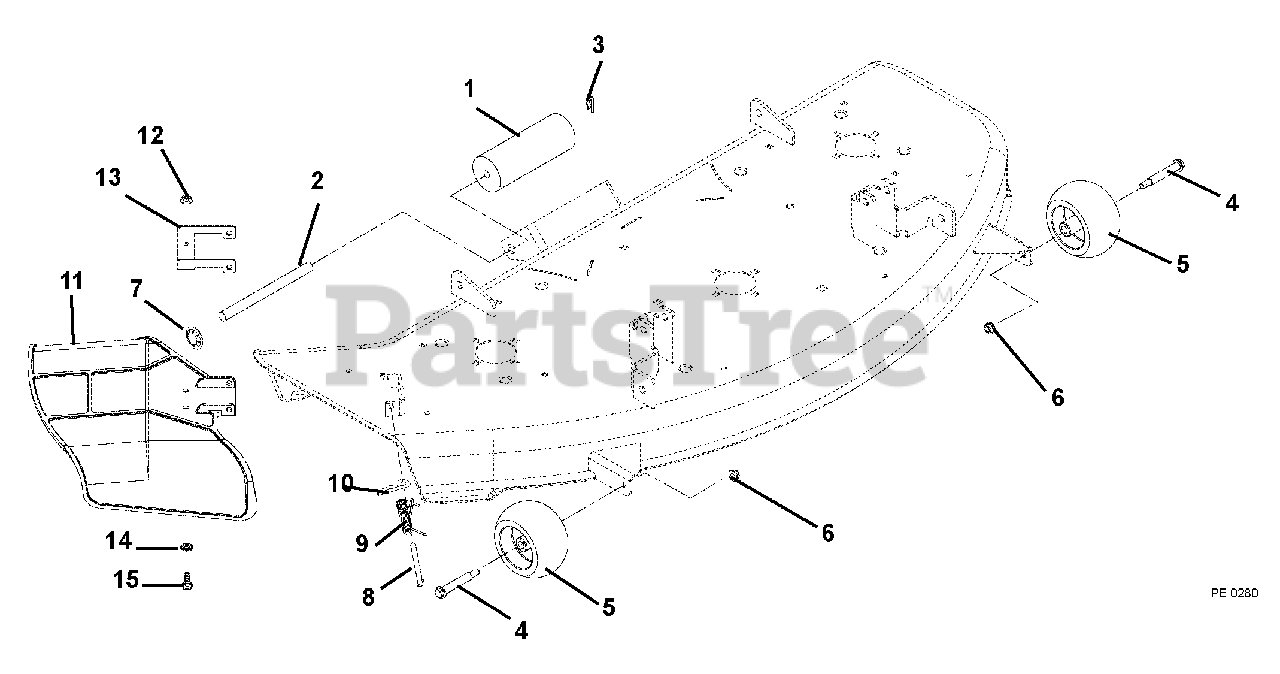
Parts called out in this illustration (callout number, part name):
1	ROLLER
2	PIN, ROLLER
3	PIN, SPRING CLIP
4	BLT-SHLDR .38-16X2.50 HWH G5
5	WHEEL 5 X 3
6	@NUT-LK-TOP-FLG .38-16 YWZC
7	PUSH NUT, .625 SHAFT
8	PIN, 5/16 X 3.88"
9	SPRING, TORSION
10	PIN-HAIR INT .08X.18X1.18 YWZC
11	MOLDED CHUTE, ZOOM
12	@NUT-LK-TOP-FLG .31-18 YWZC
13	CHUTE REINFORCEMENT
14	@WSHR-FL-STL.38X.875X.083 YWZC
15	SCR-SKH .31-18X.75 BTNHD YWZC
